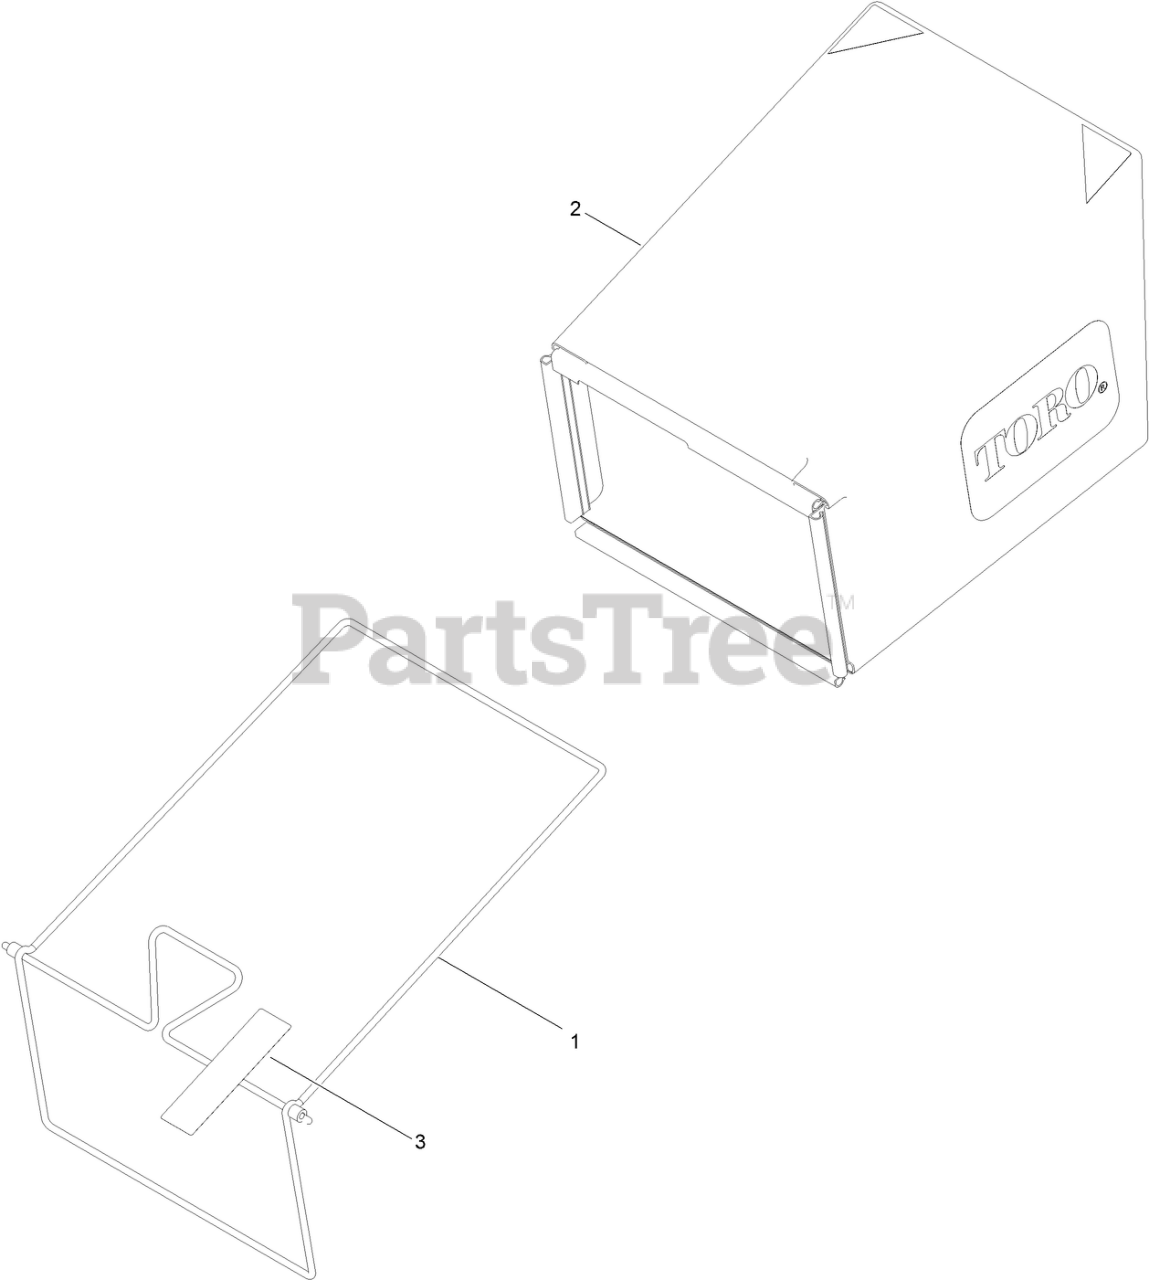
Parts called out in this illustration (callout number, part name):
1	FRAME-BAG
2	BAG-GRASS
3	Decal-Warning
